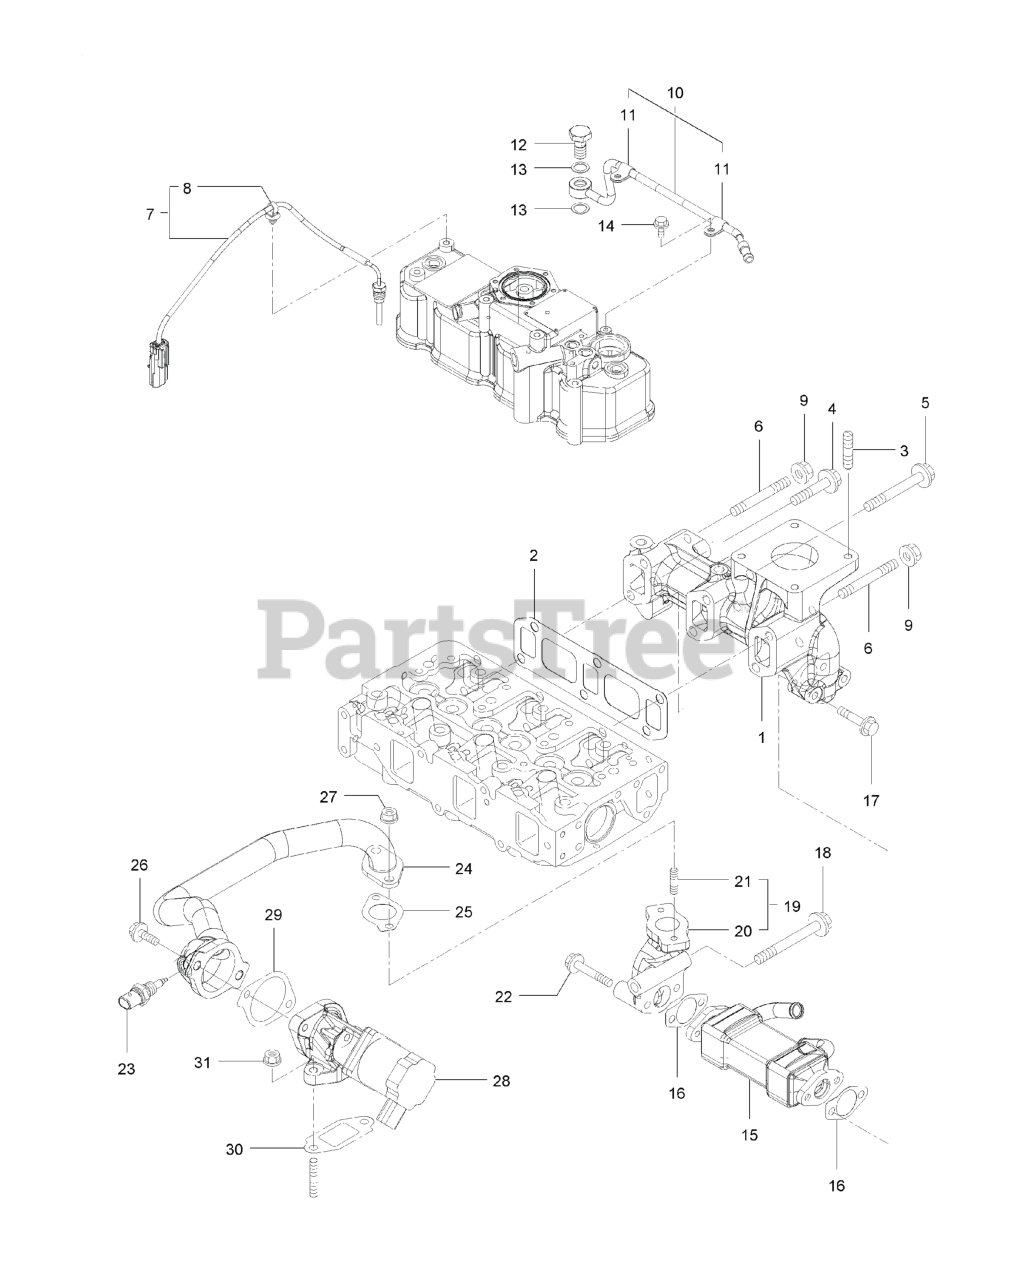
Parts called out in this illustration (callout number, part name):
1	MANIFOLD-EXHAUST
2	GASKET-MANIFOLD, EXHAUST
7	SENSOR-TEMP, EXHAUST
8	BAND-CLIP
10	Exhaust Pipe ASM
12	BOLT-JOINT, PIPE
15	COOLER-E G R
16	GASKET-COOLER, E G R
19	E G R Pipe ASM
20	Pipe-Out, E G R
23	SENSOR-GAS TEMP, E G R
24	E G R PIPE ASM
28	VALVE-E G R
29	GASKET-INTAKE VALVE, E G
30	GASKET-OUT VALVE, E G R
